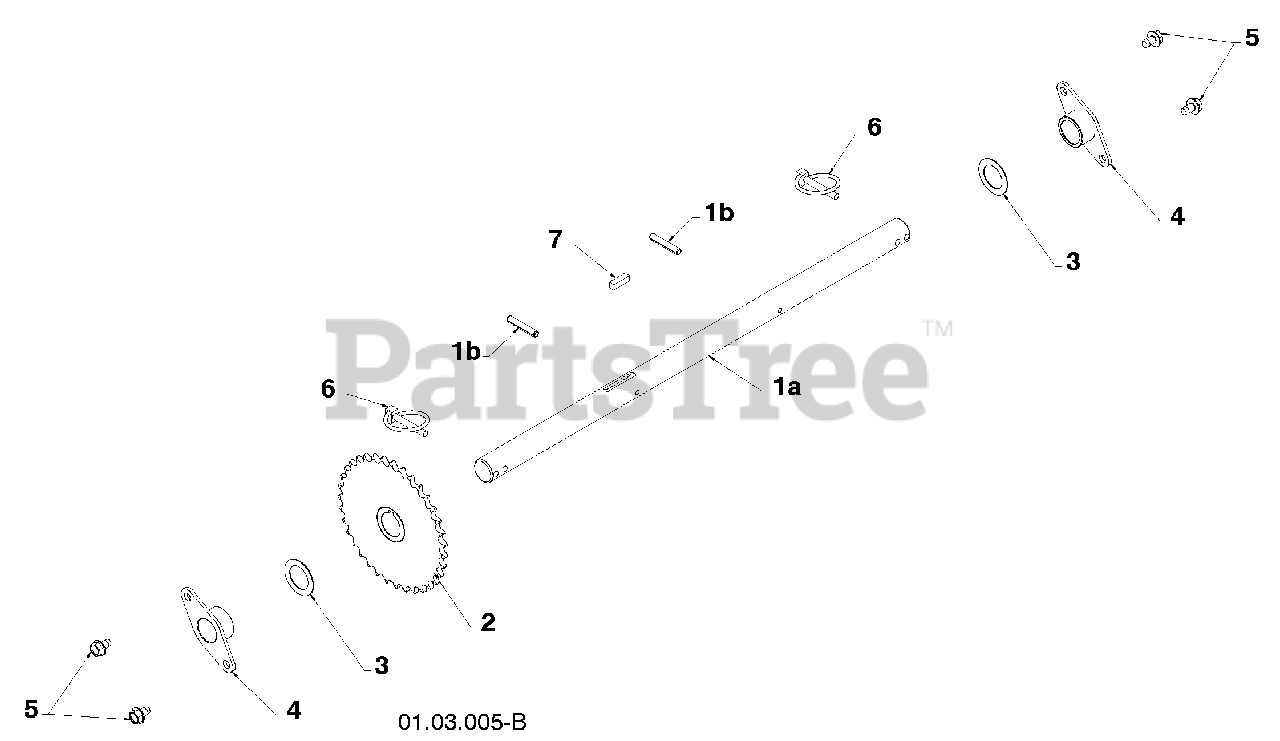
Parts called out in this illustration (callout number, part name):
1	AXLE ASSEMBLY (assy of 1a,1b)
2	SPROCKET
3	THRUST WASHER
4	BEARING
5	BOLT 5/16-18 X .500
6	CLIK PIN
7	SQUARE KEY
